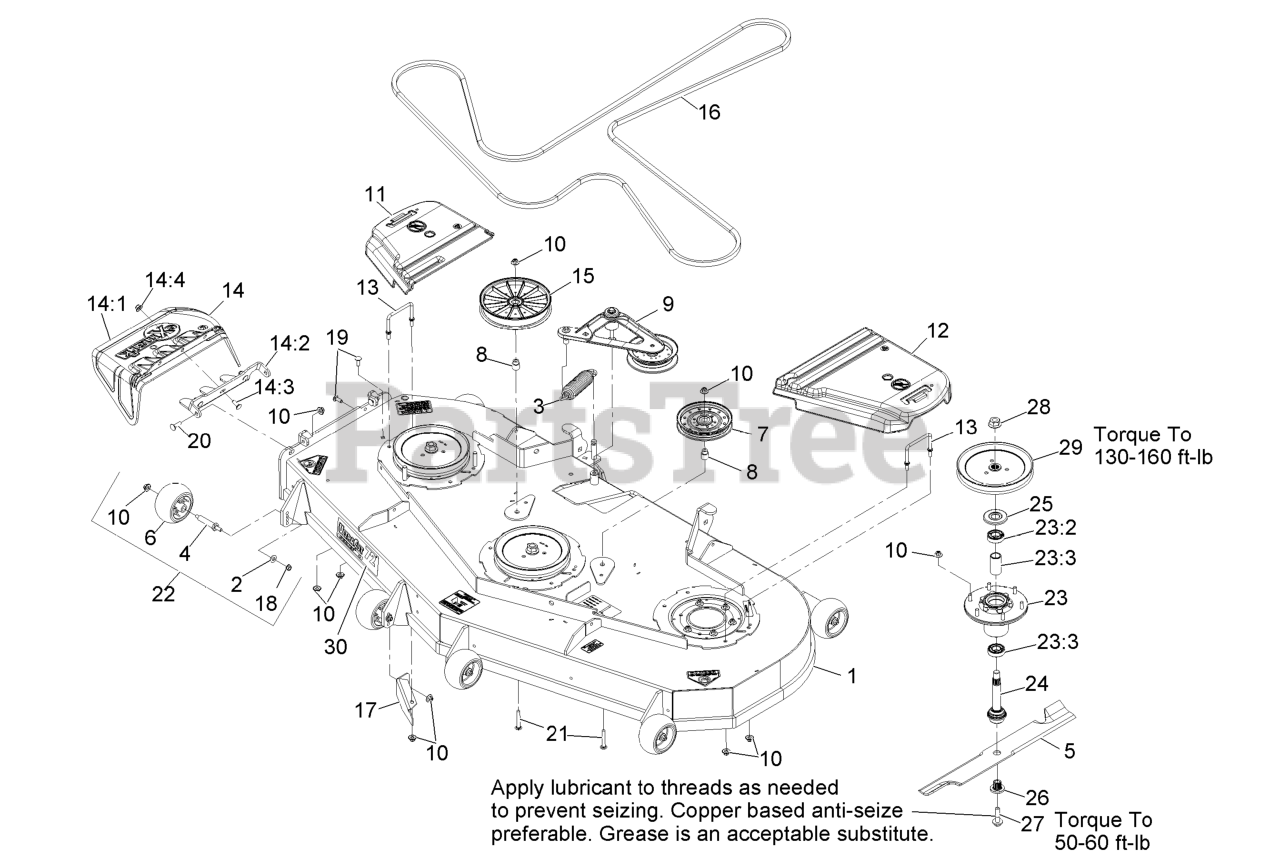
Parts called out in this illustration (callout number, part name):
1	ASM,DECK W/DECALS 724
2	WASHER-BELLEVILLE
6	ROLLER-SCALP, ANTI
8	BUSHING-IDLER
9	DECK IDLER ASM
10	Nut-Nyloc 3/8-16 Flg
11	COVER-BELT, RH
12	COVER-BELT, LH
13	WIREFORM-COVER
14	ASM,DISCHARGE CHUTE
14:1	CHUTE,DISCHARGE
14:2	BRACKET,DISCHARGE CHUTE
14:3	SCREW-CARR
14:4	Nut-Nyloc 3/8-16 Flg
15	PULLEY,IDLER 8"FLAT
16	BELT-V
17	BAFFLE,DISCHARGE 726
18	NUT-HHF, WHIZ
19	SCREW-CARR
20	Bolt-Carriage 3/8-16 X 1 1/4
21	SCREW-CARR
23	ASM-CUTTER HSG WITH BEARINGS
23:2	BEARING-BALL
23:3	SPACER-BEARING
24	ASM-SPINDLE AND SEAL
25	GUARD,BEARING TOP .989
26	BUSHING,SPLINED
27	SCREW,SEMS 1/2-20 X 2.19
28	NUT-FLANGE
29	SHEAVE,BLADE DRIVE 8.74
30	DECAL,ULTRACUT 72 SERIES
